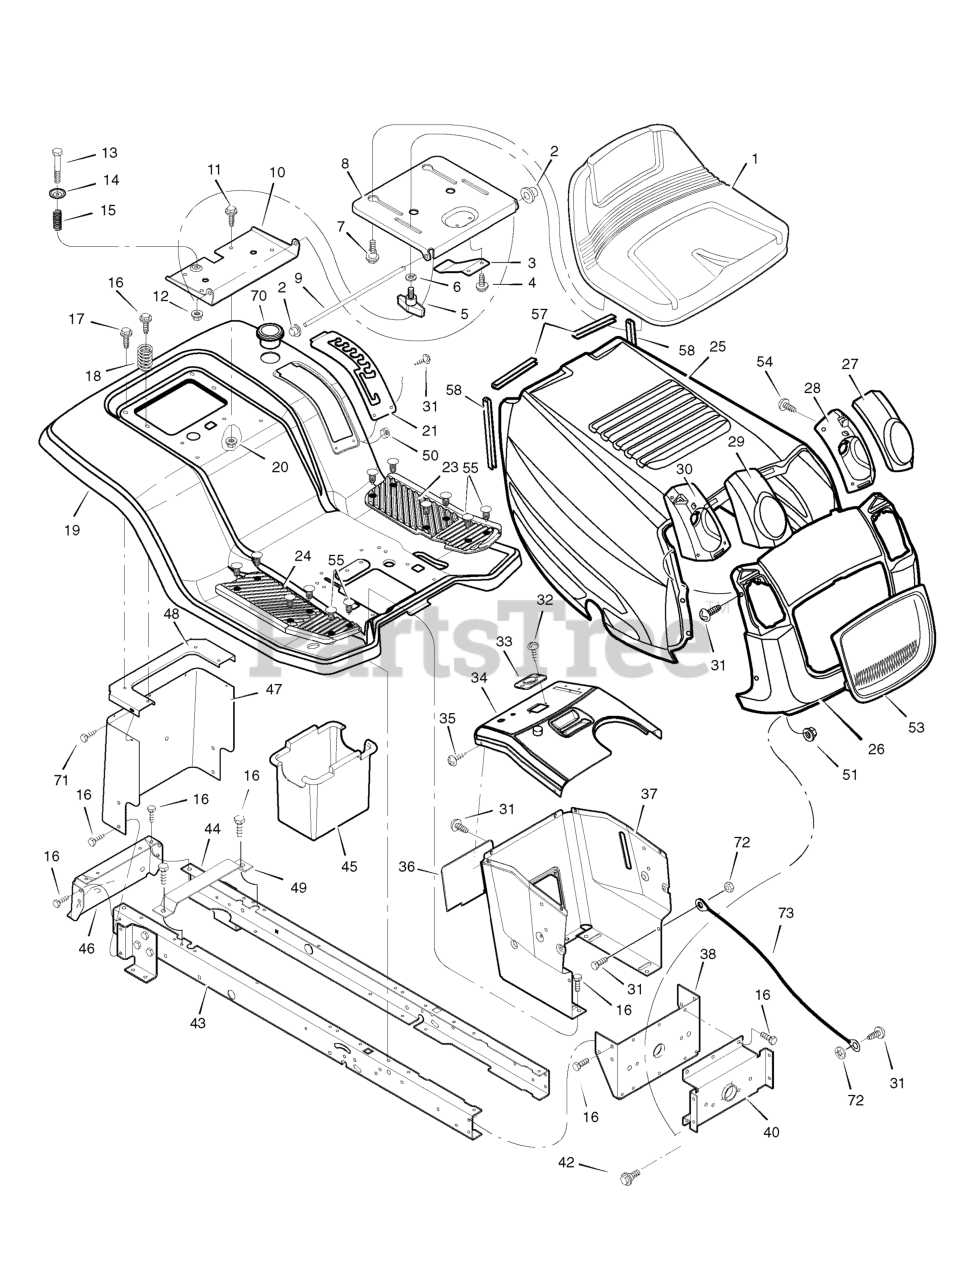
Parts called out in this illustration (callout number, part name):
1	Seat
2	Cap, Push 0n
5	Bolt, Wing
6	Washer
7	Bolt, Shoulder
8	Support, Seat
9	Rod, Pivot
10	Bracket, Pivot
11	Bolt
13	Bolt, Shoulder
20	Nut
21	Plate, Lift
23	Mat, Left
24	Mat, Right
27	Lens, Left
28	Housing, Left Headlamp
29	Lens, Right
30	Housing, Right Headlamp
33	Bearing, Steering
36	Panel, Access
37	Support, Dash
38	Bracket, Rear Hanger
40	Axle, Hanger
42	Bolt, Shoulder
43	Frame, Right
44	Frame, Left
45	Container, Battery
46	Plate, Hitch
47	Plate, Rear
48	Top, Rear Plate
49	Bracket, Battery Support
51	Nut
53	Insert, Grille
55	Fastener, Panel
57	Trim, Hood (3.75")
58	Trim, Hood (6.5")
70	Holder, Cup
71	Screw
72	Push, Retainer .250
73	Lanyard 31.5
